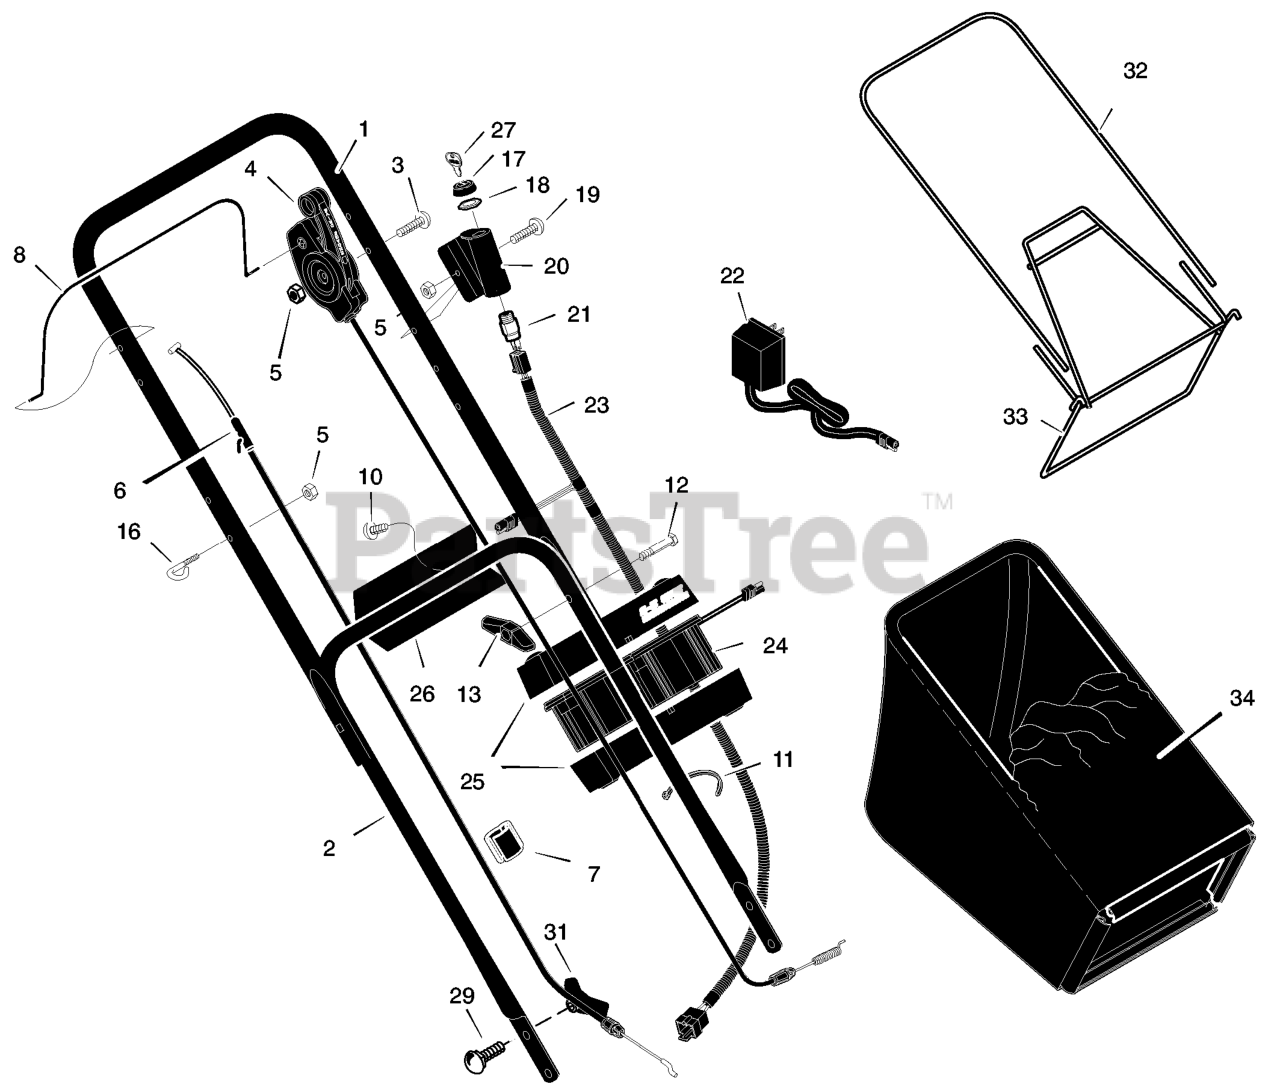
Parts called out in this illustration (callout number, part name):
1	Handle, Upper
2	Handle, Lower
4	Control, Drive
5	Locknut
6	Cable, Stop
7	Fastener, Cable
8	Lever, Stop
11	Fastener, Cable
13	Knob
16	Guide, Rope
17	Cap
18	Nut
20	Cover, Ignition
21	Switch Ignition & Key
22	Charger, Battery
23	Harness, Wiring
24	Battery
25	Case, Battery
26	Bracket, Battery
27	Key, Ignition
29	Bolt, Carriage
31	Knob, Plastic
32	Tube, Bag
33	Frame Assembly
34	Bag, Cloth
